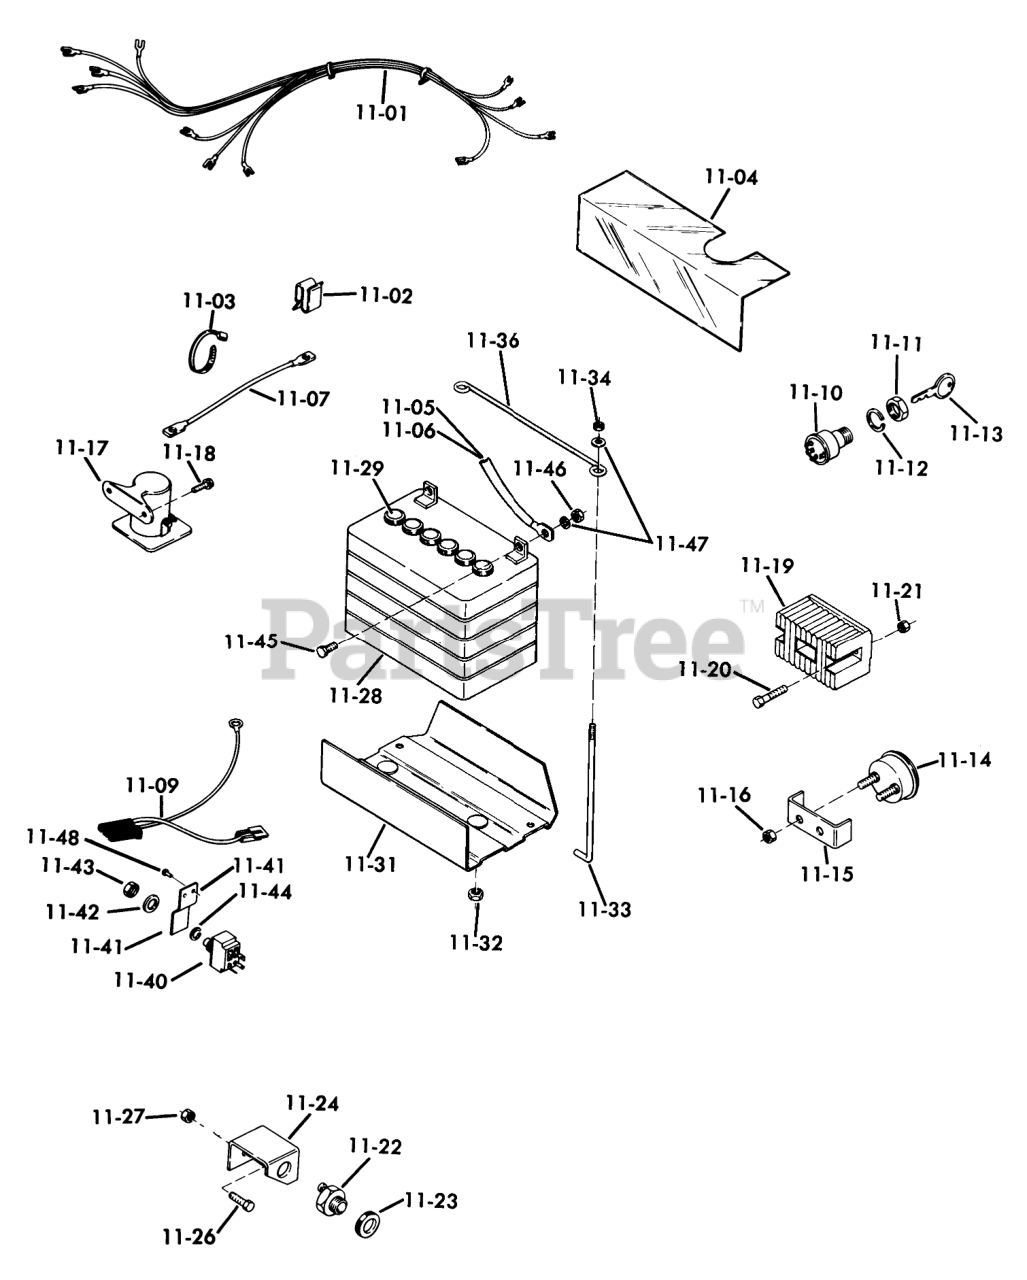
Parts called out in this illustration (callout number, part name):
11-01	WIRING HARNESS & DIA
11-01	Wiring Harness
11-01	MODULE-INTERLOCK
11-02	SPEED CLIP
11-03	PLASTIC TIE
11-03	Cable Tie
11-04	Wire
11-05	Wire
11-06	WIRE SOLENOID
11-07	Wire
11-09	Wire Assembly-Interlock to Harness
11-10	SWITCH-IGNITION
11-10	SWITCH
11-12	LOCKWASHER
11-13	Key-EL
11-13	KEY SWITCH
11-14	AMMETER W/CLAMP
11-15	Clamp
11-16	HEX NUT 10-32 E.S.
11-17	Solenoid
11-18	Screw
11-19	REGULATOR-RECTIFIER
11-20	Bolt
11-21	Nut
11-22	SWITCH-CLUTCH
11-23	NUT-SPECIAL 9/16-18
11-24	Bracket
11-26	BOLT
11-27	Nut
11-28	Battery
11-31	Battery Box
11-32	Nut
11-33	Hook
11-34	Nut
11-36	ROD-HOLD DOWN
11-40	SWITCH-CLUTCH
11-40	SWITCH SAFETY
11-41	SWITCH-INTERLOK CLUT
11-42	WASHER
11-43	NUT-HEX
11-43	NUT-SPECIAL 9/16-18
11-44	TAB-WASHER
11-45	Bolt
11-46	Nut
11-48	RIVET
